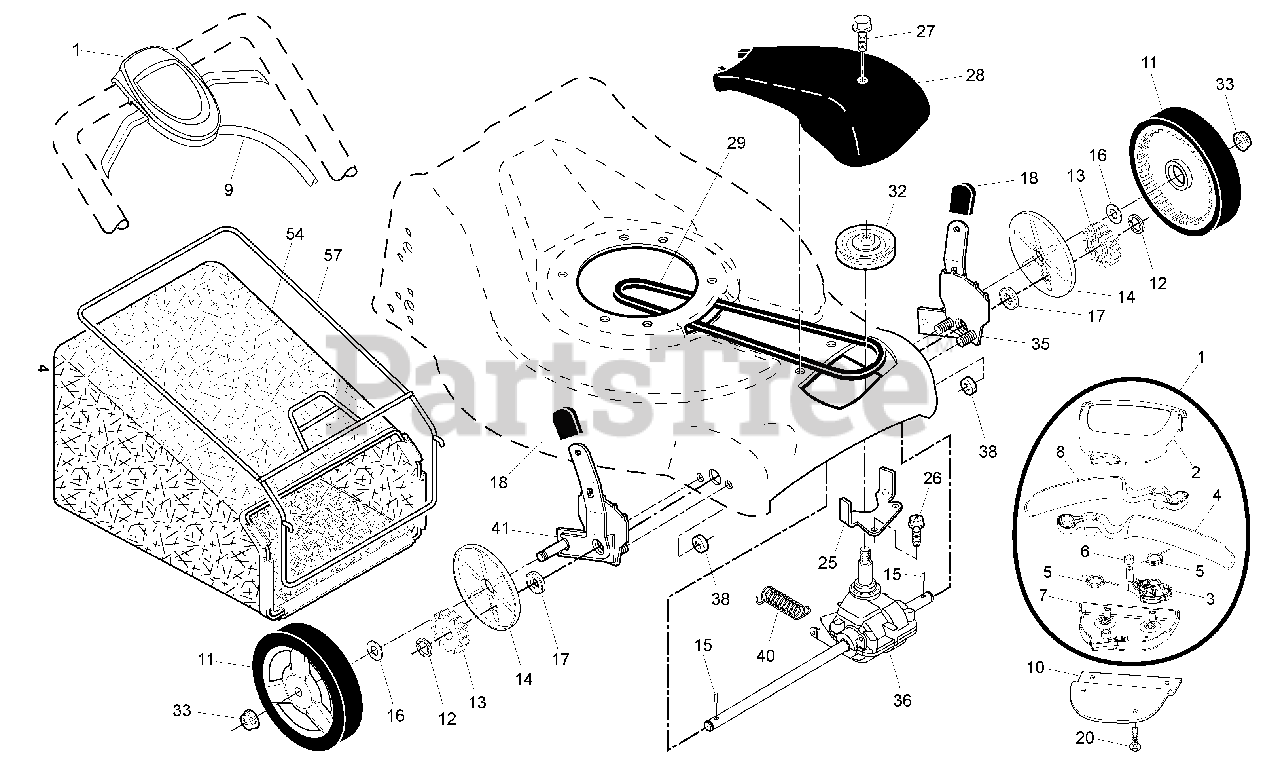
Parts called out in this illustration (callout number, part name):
1	Drive Control Assembly
2	Cover, Drive Control, Upper
4	Lever, Drive Control, LH
7	Cover, Drive Control, Lower
8	Lever, Drive Control, RH
9	Cable, Drive Control
10	Mounting Bracket, Drive Control
11	Wheel & Tire Assembly
14	Dust Cover
15	Pawl, Drive
16	Washer 1/2 x 1-1/2 x .134
17	Bearing, Wheel Adjuster
18	Selector Knob
25	Belt Keeper
26	Screw, Hi-Lo Thread #12 x 5/8
28	Drive Cover Assembly
32	Pulley, Drive
33	Locknut, Hex
35	Kit, Wheel Adjuster, LH
36	Gear Case Assembly, Complete
38	Locknut 1/4-20
41	Kit, Wheel Adjuster, RH
54	Grassbag
57	Frame, Grassbag
